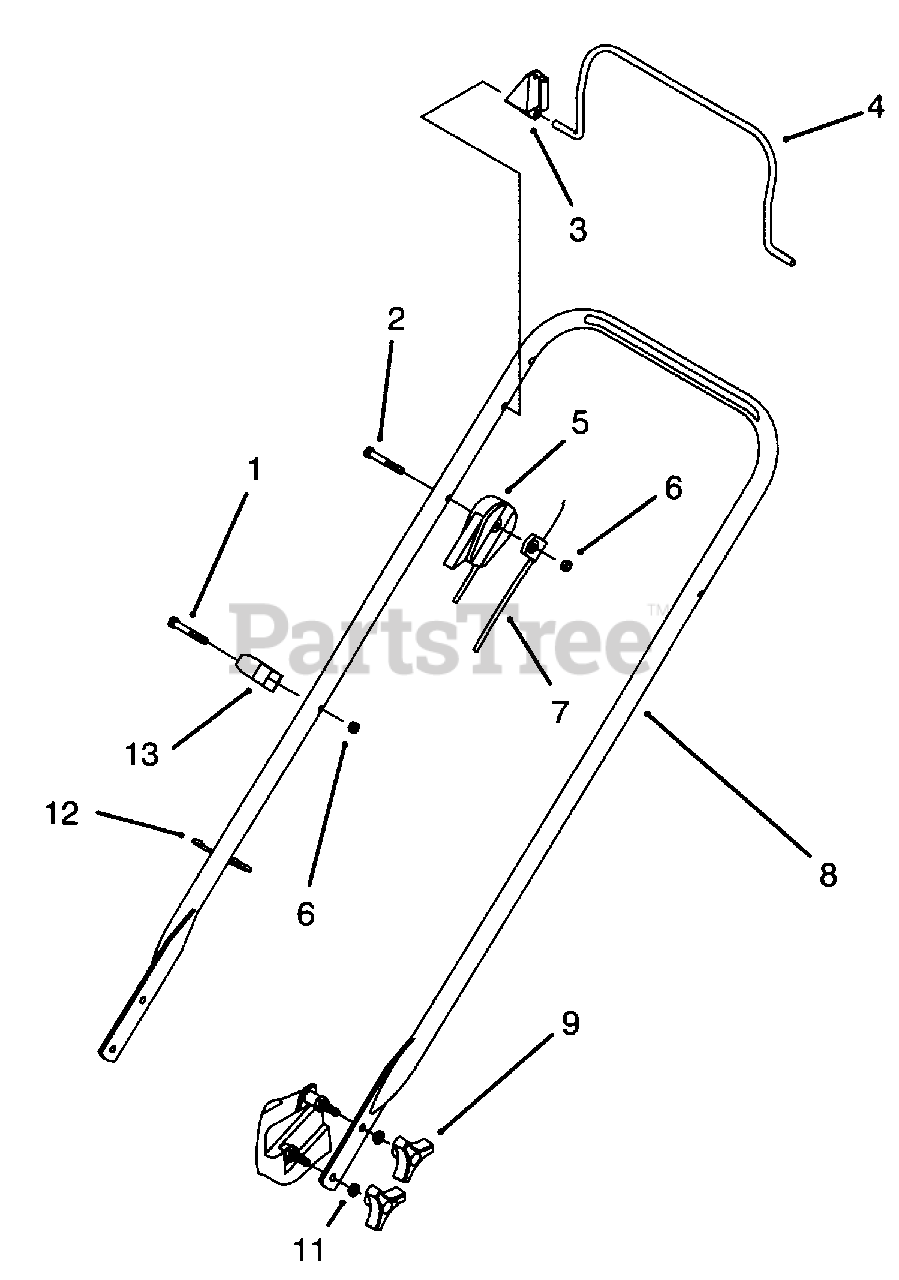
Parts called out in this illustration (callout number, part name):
1	Screw-Hex Hd. Cap
2	Screw-Hex Hd. Cap
3	Stop-Pivot
4	Bail-Flywheel Brake
5	Cable-Throttle
6	Nut-Lock
7	Cable-Flywheel Brake
9	Knob
11	Washer-Lock
12	Tie-Cable
13	Guide-Rope
